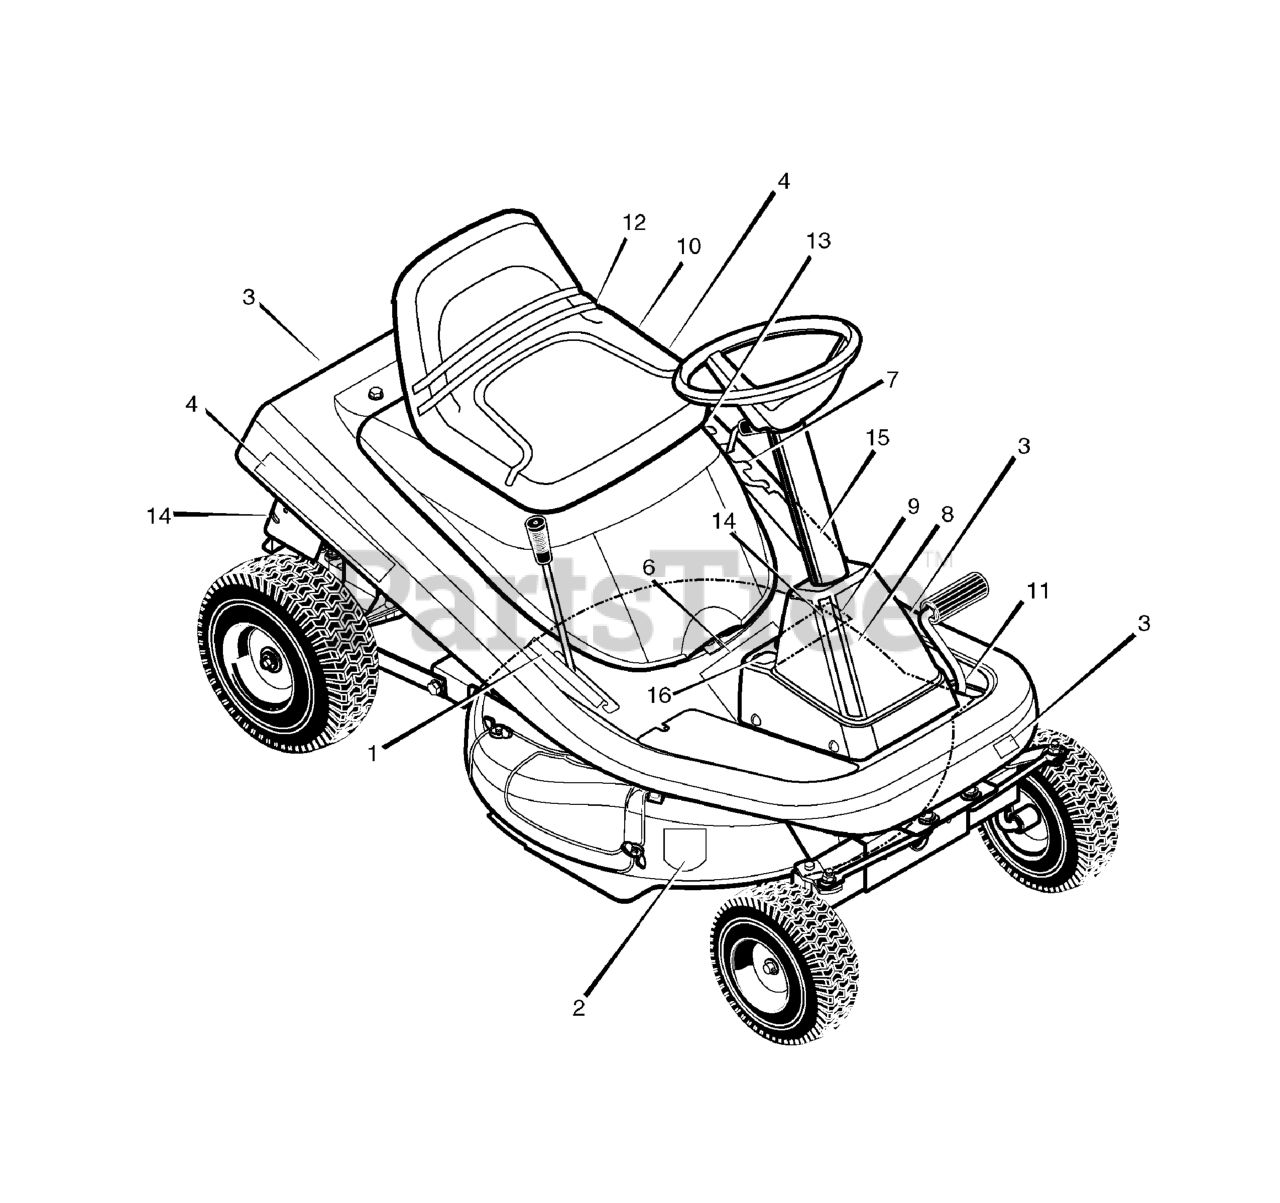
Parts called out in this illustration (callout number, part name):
1	DECAL, Engagement
2	DECAL, English Cut Finger
3	DECAL, Turf Master
4	DECAL, Turf Master
6	DECAL, Warning
7	DECAL, Height Adjust
8	DECAL, Caution, No Step
9	DECAL, Parking Brake Symbol
10	DECAL, Throttle Control
11	DECAL, Clutch Brake
12	DECAL, Gas Gauge
14	DECAL, Drawbar Warning
15	DECAL, Deck Level Position
16	DECAL, Auto Disconnnect
17	DECAL, Starting Instructions
